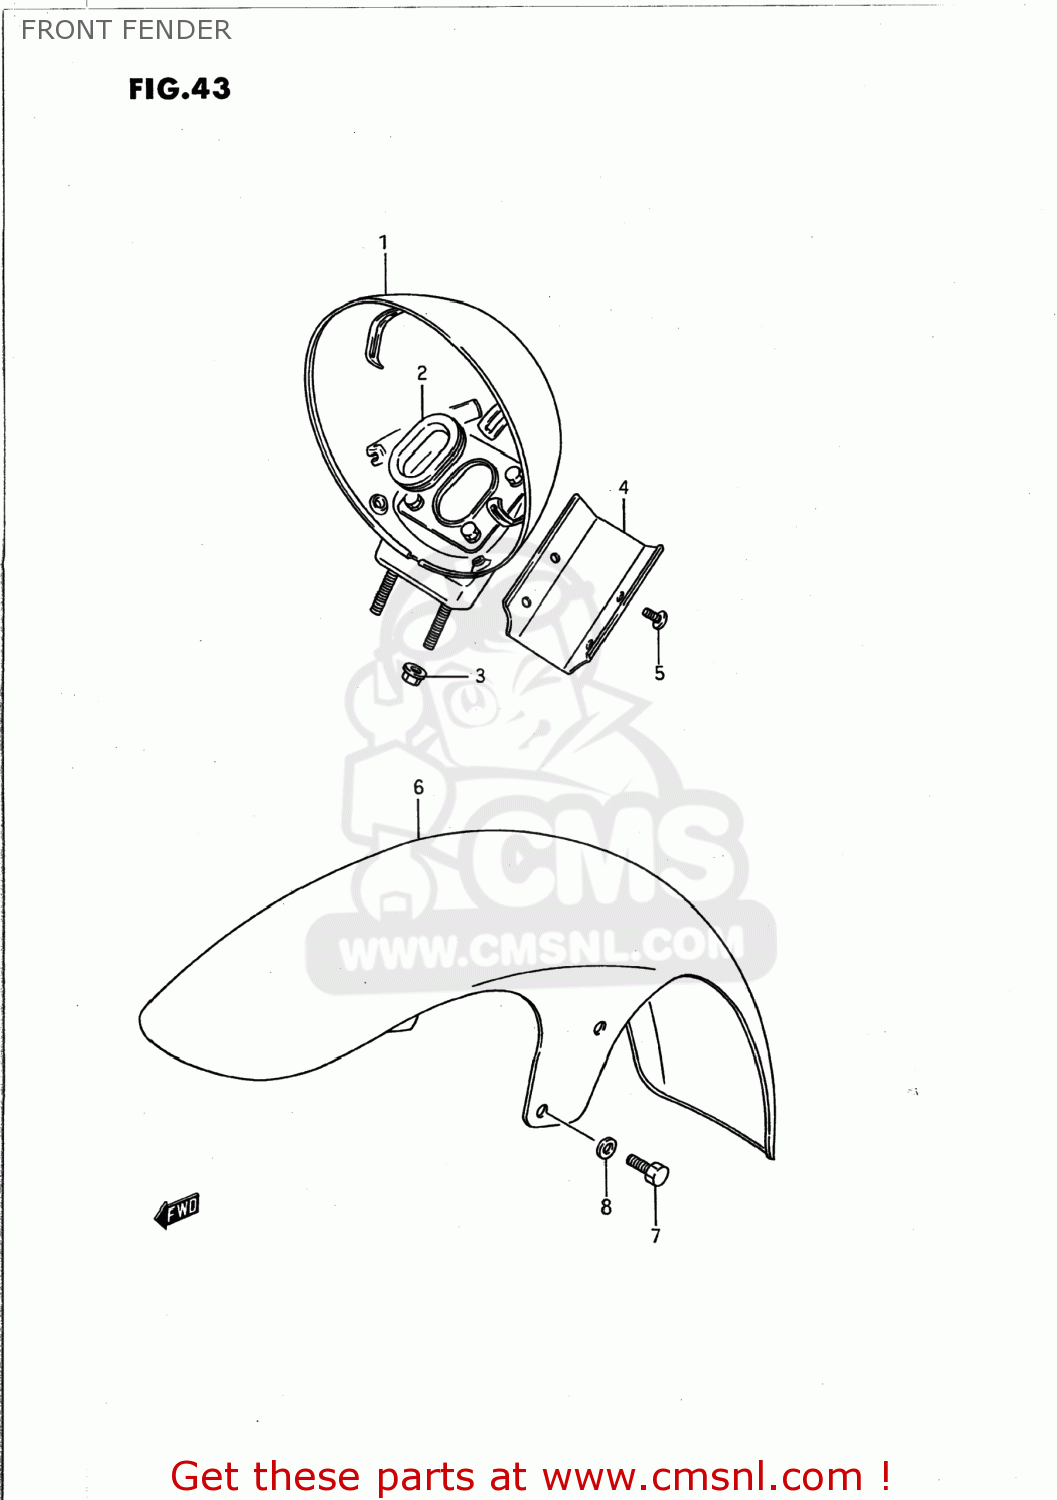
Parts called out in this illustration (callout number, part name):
1	HOUSING,HEADLAMP
2	GROMMET
3	NUT
4	COVER,HEADLAMP HSG
5	SCREW
6	FENDER COMP,FRONT
7	BOLT
8	WASHER,LOCK
